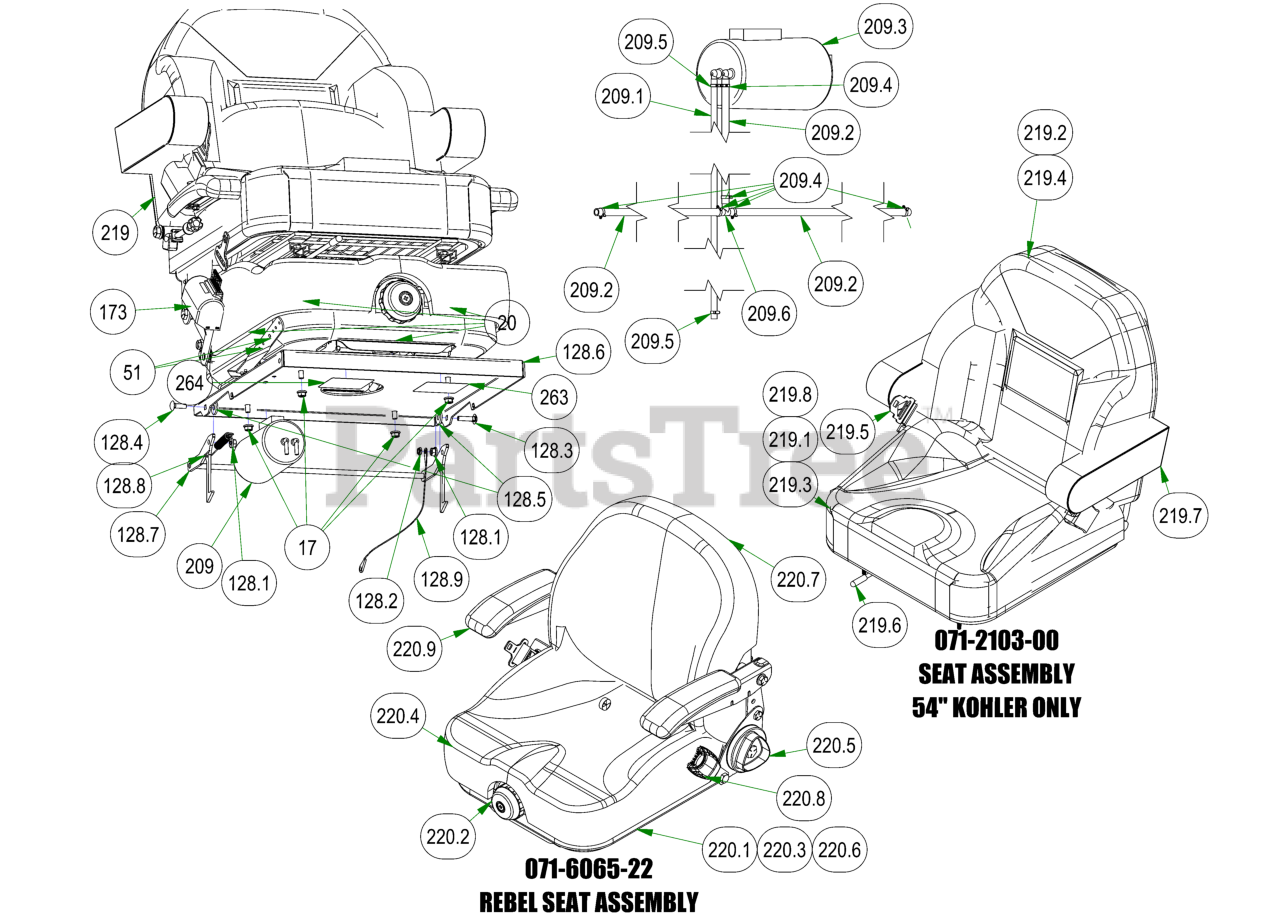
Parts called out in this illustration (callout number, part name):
17	5/16-18 NYLON INSERT FLANGE LOCKNUT ZINC
20	5/16-18 HEX SERRATED FLANGE NUT HARD/ZINC
51	M6-1.0 X 16MM DIN 933 HEX TAP BOLT (CL 8.8) ZINC
128	R-SERIES SEAT PLATE ASSEMBLY
128.1	5/16-18 NYLON INSERT FLANGE LOCKNUT ZINC
128.2	5/16-18 NYLON INSERT JAM LOCKNUT ZINC
128.3	5/16-18 X 1-1/4 CARRIAGE BOLT ZINC
128.4	5/16-18 X 1 CARRIAGE BOLT (GR.8) ZINC
128.5	.360 ID X .983 OD X .120 THICK FLAT WASHER NYLON
128.6	R-SERIES SEAT PLATE
128.7	Seat Latch Rod Assembly
128.8	Brake Spring
128.9	Seat Cable
145	1/4-14 X 1-1/2 HEX WASHER UNSLOT TEK/3 ZINC
209	2019 Outlaw EPA Cannister Assembly
209.1	3/16" Vinyl Tubing, 66" Long
209.2	1/4" Vinyl Tubing 38" Long
209.3	Carbon Canister
209.4	3/16 Vinyl Clamp
209.5	3/16" Vinyl Hose Clamp
209.6	fuel line T
218	2022 Rebel Frame
219	2021 Rebel Seat
219.1	Seat Cover for 071-2103-00
219.2	Back Cover for 071-2103-00
219.3	Foam Molded Seat for the 071-2103-00
219.4	Foam Molded back for the 071-2103-00
219.5	Seat Belt Set 071-2103-00
219.6	Seat Rails for Outlaw Seat/2020 ZT Elite/ZTAvenger
219.7	Arm Rest Kit for 071-5060-18
219.8	Set Switch fr 071-5060-18
220	2022 Suspension Seat w/Seatbelt
220.1	4" Single Locking Track Kit
220.2	Weight Adjust Indicator Knob Assy
220.3	Bellows w/Hardware
220.4	Cushion Cover Kit for I3M-Logo
220.5	Recliner Adjustment Knob-New
220.6	Delta Plunger Switch - N.O.
220.7	Back Cover for I3M - Recl - Logos
220.8	2" Retractable Belt Kit w/Spacers
220.9	Set of Armrests-SS Front Adj
263	Control Adj. Control Rod Decal
264	Control Adj. Control Dampener Decal
